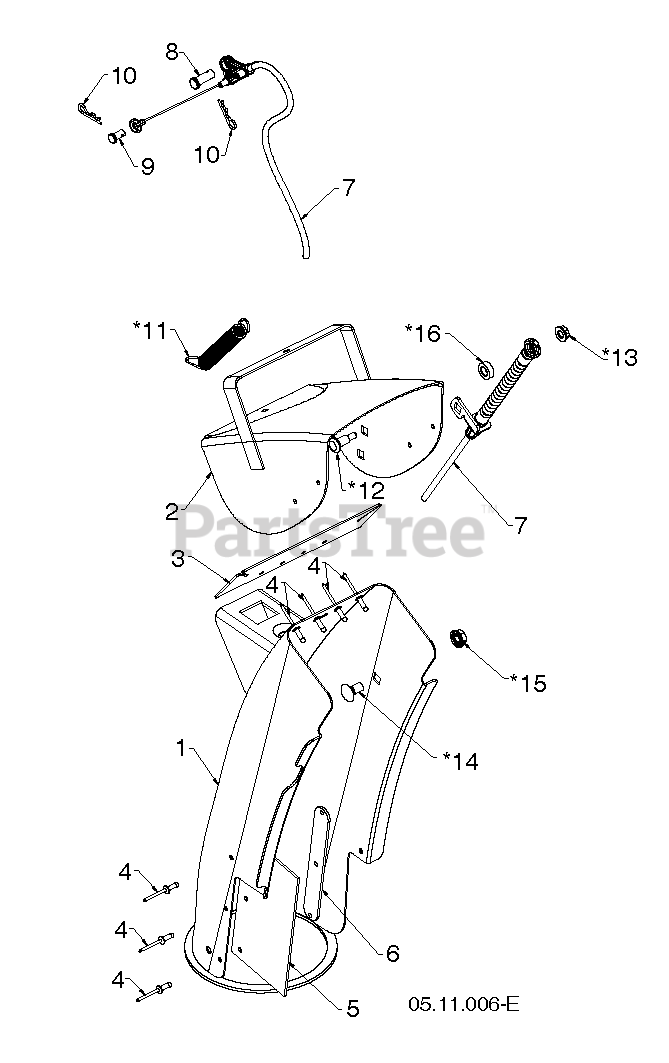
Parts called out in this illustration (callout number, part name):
1	ASM.CHUTE/DEFLECTOR.428
7	CABLE.CONTROL.CHUTE.DEFLEC
8	PIN CLEVIS 5/16X.875
9	PIN CLEVIS .25 X .31
10	HAIRPIN.SOFT.ZINC.059X1.125
